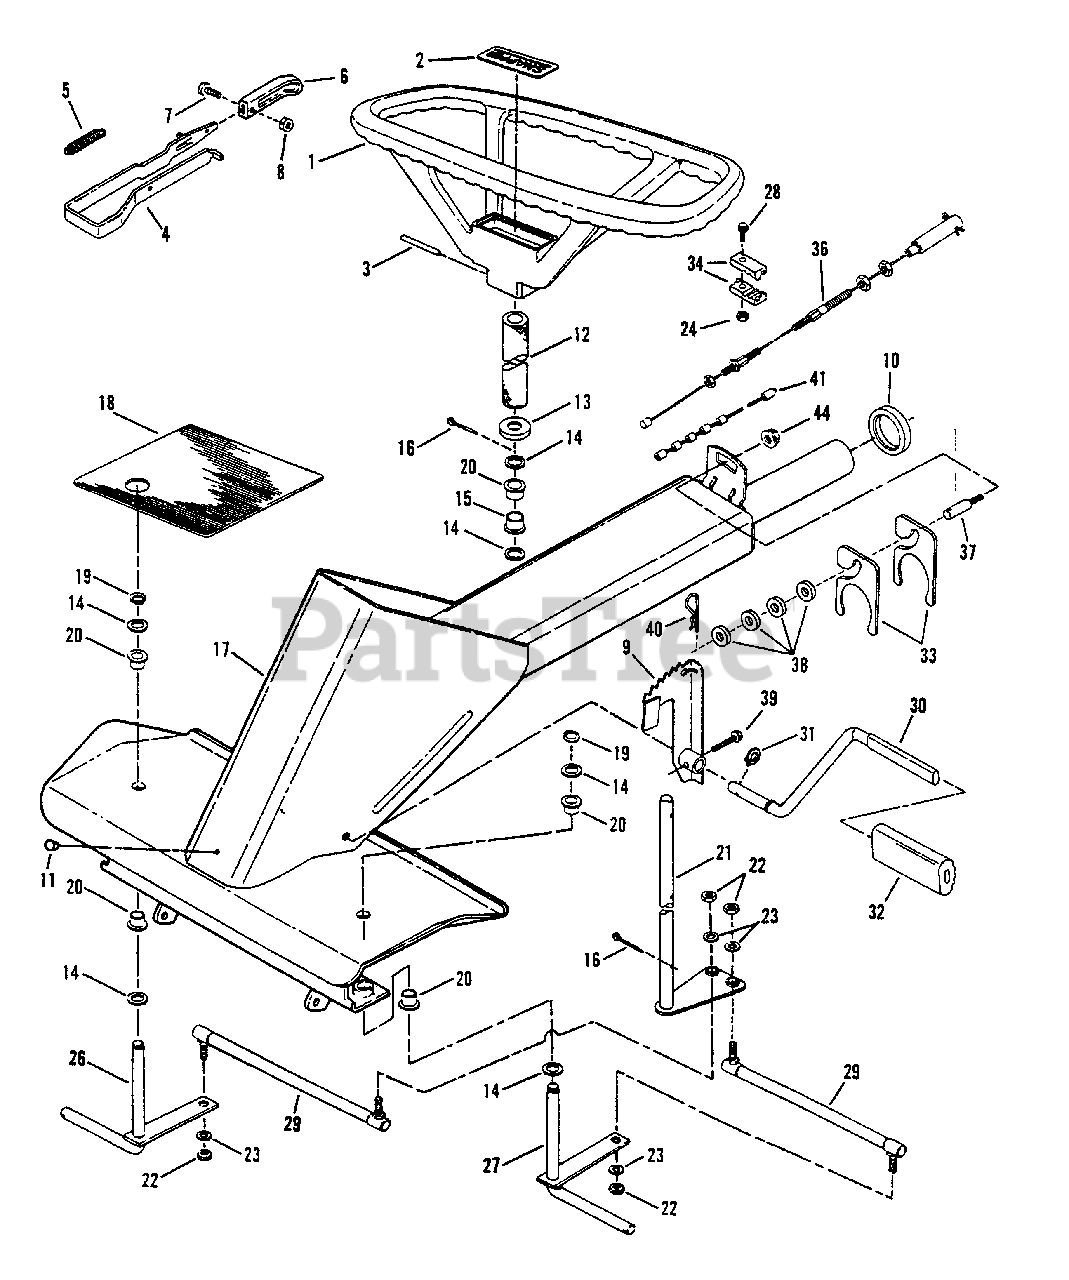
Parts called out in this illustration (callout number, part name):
1	ASSEMBLY, Steering Wheel
2	DECAL, Snapper
3	PIN, 1/4 x 1-1/2" Roll
4	BRACKET, Clutch/Brake
5	SPRING
6	KNOB
7	SCREW, #8-32 x 3/8" Cross Recess
8	NUT, #8-32 Hex
9	ARM, Clutch/Brake
10	SPACER, Main Tube
11	PLUG
12	COVER, Steering Shaft (Foam)
13	COVER
14	WASHER, 3/4 Flat
15	BUSHING, 3/4" Steering Shaft
16	PIN,3/16 x 1-1/2" Cotter
17	FRAME, Front
18	PAD, Foot (Right Side Shown)
19	RING, Retaining
20	BEARING
21	SHAFT, Steering (Wide Front End)
22	NUT, 5/16-24 Hex
23	WASHER, 5/16 Split Lock
24	NUT, 1/4-20 Hex Center Lock
25	NUT, 3/8-24 Hex Flange Lock
26	PIN, Wide King (Right Side)
27	PIN, Wide King (Left Side)
28	BOLT, 1/4-20 x 3/4" Hex Flange Lock
29	TIE-ROD (42" Models)
30	PEDAL, Clutch/Brake
31	RING, 5/8" External Retaining
32	PAD, Clutch/Brake Pedal
33	SPACER, Pivot
34	UNION, Cable
35	CABLE, Clutch
36	CABLE, Brake
37	STUD
38	SPACER
39	SCREW, 5/16-18 x 1-1/4" Self-Tapping
40	PIN, 1/8 x 2-9/16 Hair
41	CABLE, Clutch
44	NUT, 3/8"-24 Hex Flange Lock
